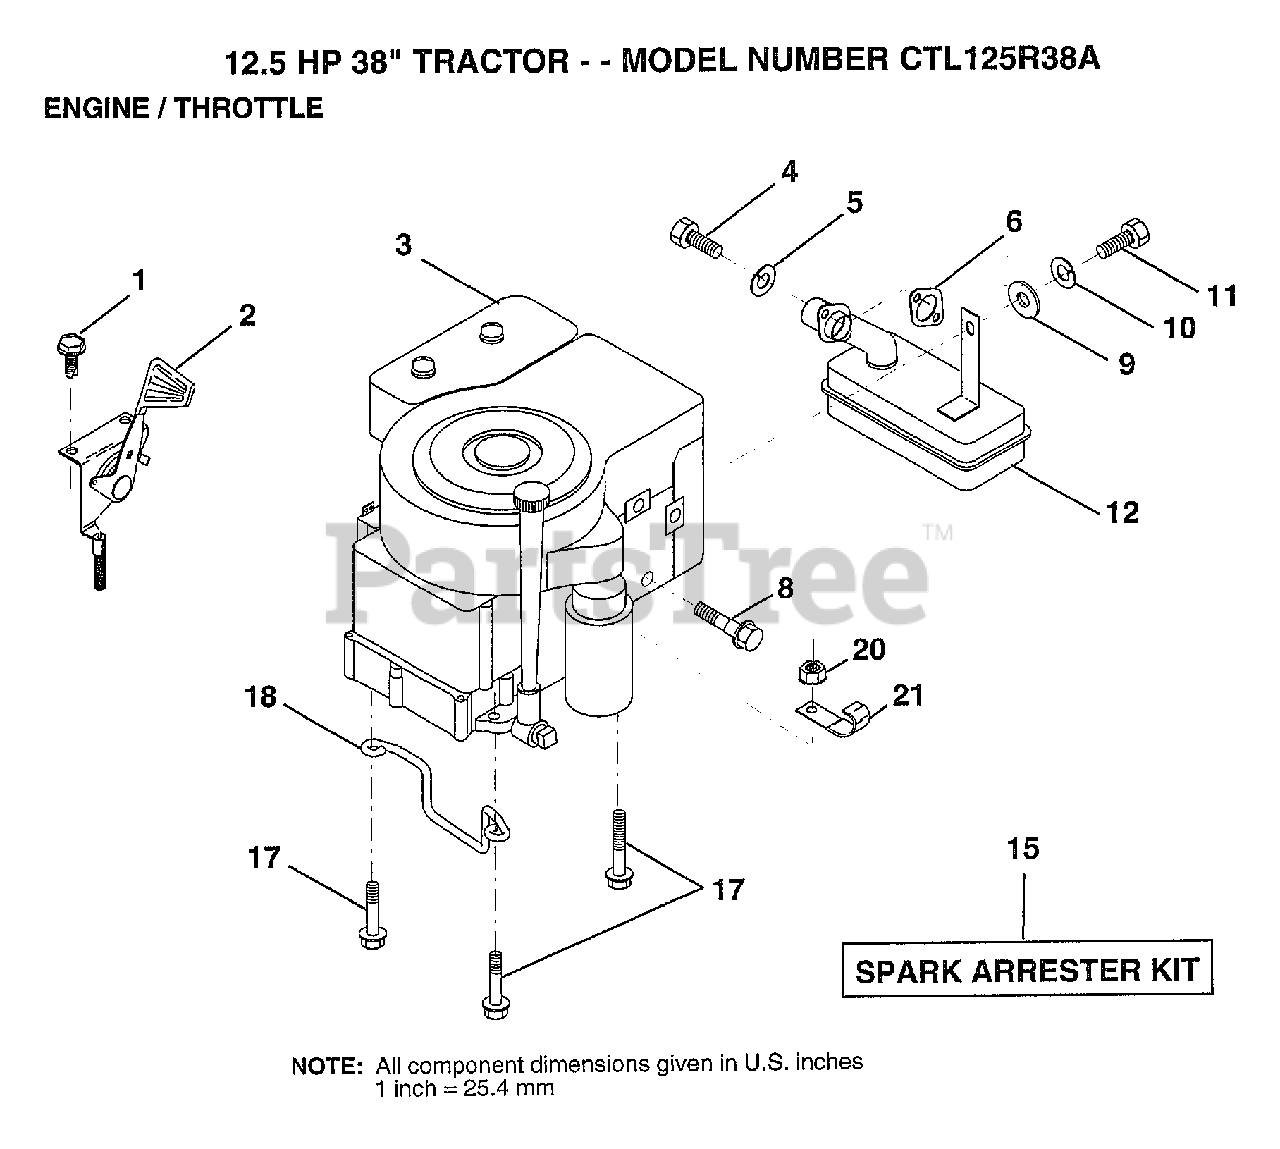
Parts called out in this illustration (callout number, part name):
1	SCREW.1/4-20X1/2
2	"CONTROL,THROTTLE"
4	SCREW
5	LOCKWASHER
8	BOLT T
10	LOCKWASHER
12	MUFFLER
17	SCREW LT
18	"KEEPER,DR BELT GR"
20	NUT
21	CLIP T
